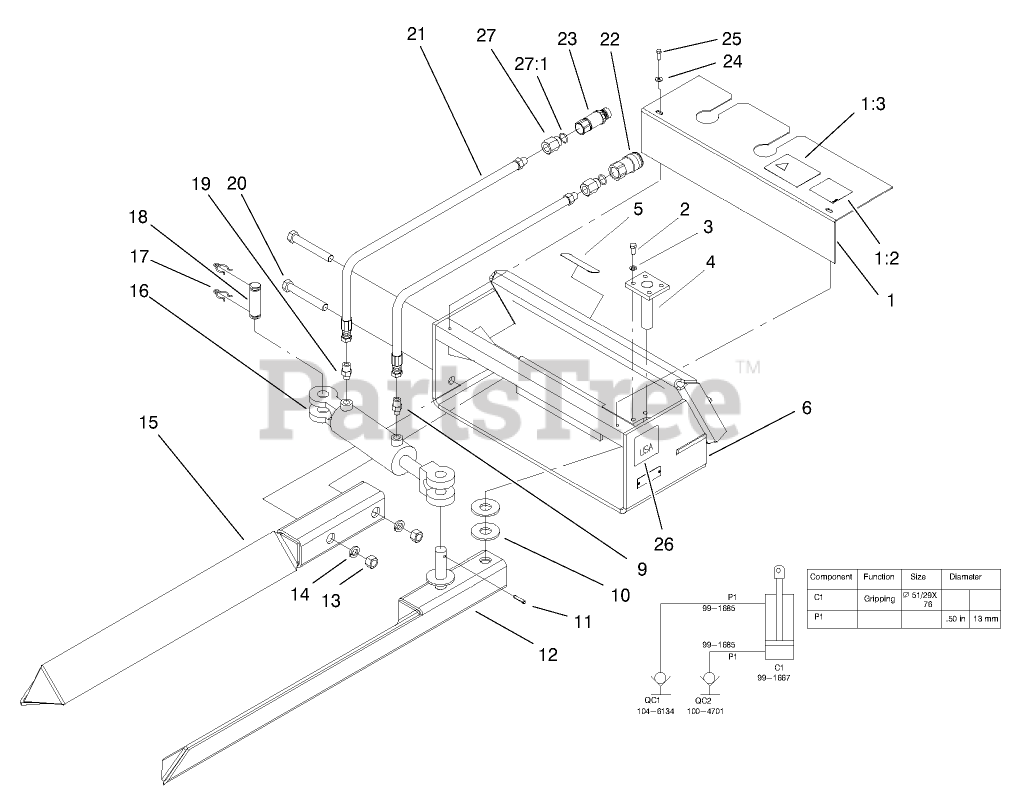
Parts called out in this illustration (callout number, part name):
1	SHIELD ASM
1:2	DECAL-WARNING
1:3	DECAL-RATING, LOAD
2	SCREW-HSH
3	WASHER-LOCK
5	Decal
6	FRAME
9	CONNECTOR - STRAIGHT
10	WASHER-FLAT
11	PIN-ROLL, SLOTTED
12	ARM-PIVOT, LH
13	NUT-HEX
14	WASHER-LOCK
15	ARM-PIVOT, RH
16	CYLINDER - TREE FORK
17	CLIP - PIN
18	PIN - CYLINDER PIVOT
19	CONNECTOR-STRAIGHT ORIFICE
20	SCREW-HH
21	HYDRAULIC HOSE ASM
22	COUPLER-FACE, FLUSH
23	NIPPLE-CONNECT, PRESSURE
24	WASHER-FLAT
25	SCREW-HSH
26	DECAL
27	ADAPTER-HYD
27:1	O-RING
